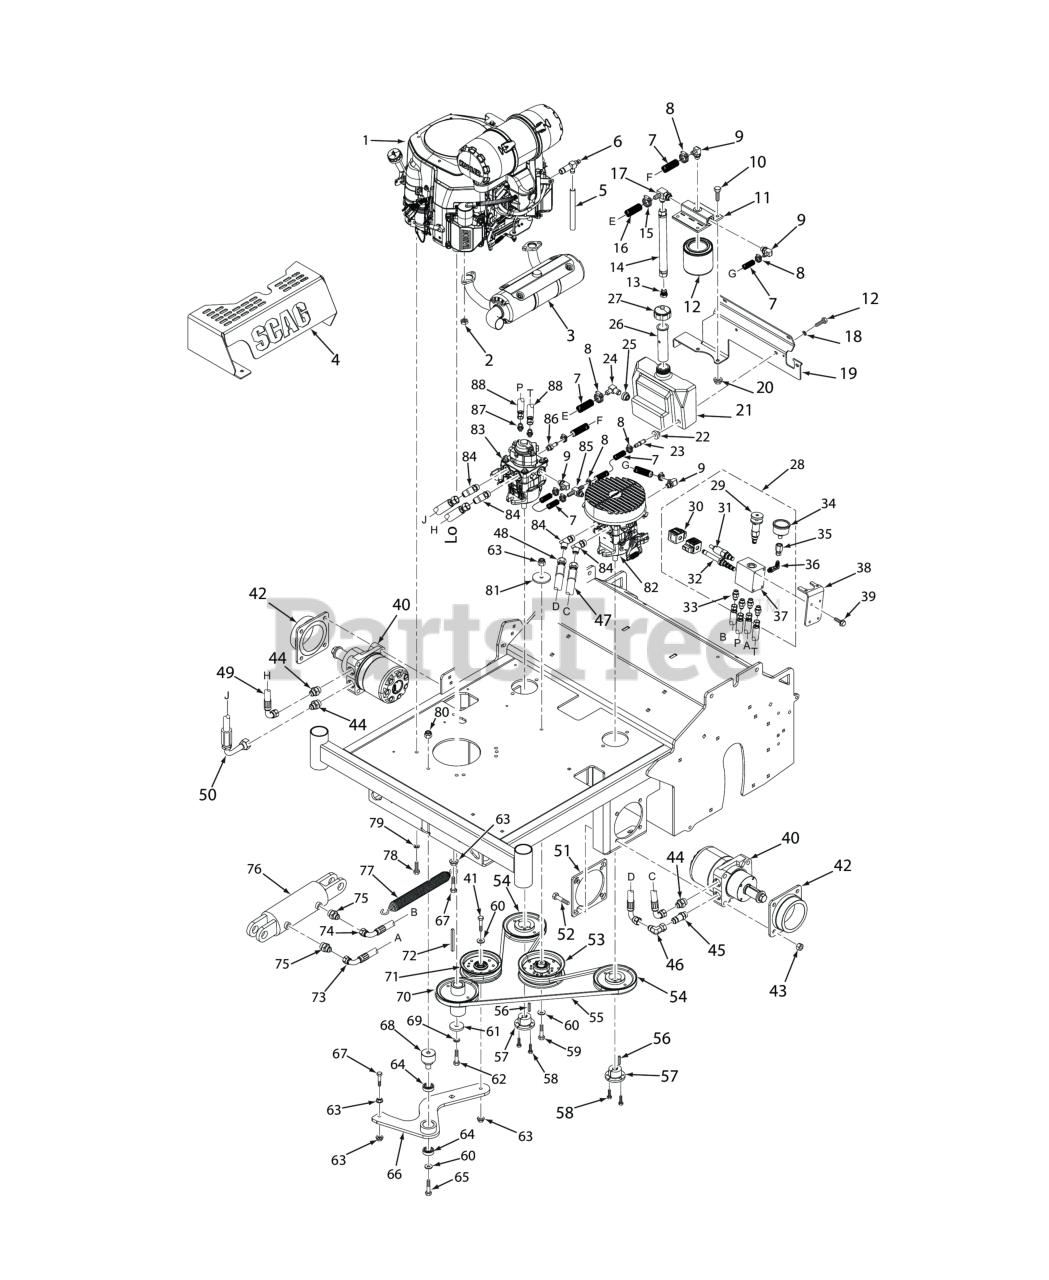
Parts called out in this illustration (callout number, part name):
1	Engine, Kohler - 23CV
2	Lock Nut, M8-1.25 -8H (Kohler)
3	Muffler, Kohler
4	Heatshield, Muffler
5	Tubing, Oil Drain 1/2 x 14"
6	Extension, Oil Drain 2.3" - Kawasaki
7	Hose, 3/8" ID - 10-1/4" Long (Order By The Inch)
8	Clamp, .69" Max. / .25" Min. Dia.
9	Elbow, 90 Degree - 9/16" O-Ring x 3/8" Hose
10	BOLT, SERRATED FLANGE HEX HEAD 5/16-18 X 3/4"
11	Filter Head Assembly
12	OIL FILTER, SPECIAL
13	Plug, JIC 3/4-16 UNF
14	Drain, Hose Assembly
15	Clamp, Cable 3/4" I.D.
16	Hose Assembly, 1/2" ID (Oil Reservoir to Filter Base)
17	Tee, 3/4" O-Ring x JIC x 1/2" Hose
18	Lockwasher, 5/16 (.317 x .586 x .078) Helical Spring
19	Bracket, Hydro Tank
20	Nut, Serrated Flange 5/16-18 (Right Front Engine Mounting, Briggs and Kohler Only)
21	Hydraulic Tank Assy.(incl. #22, 23, 24, 25, 26, 27)
22	Bushing, 0.56" Dia. Viton
23	Fitting, Straight
24	Fitting, 90 Degree - 1/2" Hose
25	Bushing
26	Insert, Filler Neck
27	CAP, HYDRAULIC TANK
28	Pressure Valve Assy. (incl. # 29 - 37)
29	Adjustable Valve Assy.
30	Adapter, Plug
31	Sensor, Valve
32	Sensor, Plug
33	Fitting, Valve
34	Pressure Gauge
35	Adapter
36	Elbow, 90 Degree O-Ring
37	Base, Valve
38	Mounting Brkt, Manifold
39	CAP SCREW, 1/4-20 X 1/2" SERRATED FLANGE HEX
40	Wheelmotor
41	Bolt, Hex Head 3/8-16 x 2-1/4" - 61"
42	Pivot Bearing Wlmt
43	Locknut, Hex 1/2-13 Center Lock
44	TUBE UNION, 3/4-16 JIC TO 7/8-14 "O" RING
45	Fitting, 1/2" JIC x 5/8" O-Ring (LH Wheel Motor - Upper Port Only)
46	Elbow, 1/2 JIC Female to 1/2 JIC Male
47	Hose Assembly
48	Hose Assembly
49	Hose Assembly
50	Hose Assembly
51	Plate Weldment, Motor Backing
52	Bolt, Hex Head 1/2-13 x 2-3/4" (48V & 52V - One Weight)
53	Idler Pulley, Belt Clutch
54	Pulley, 5.45 OD - Tapered Bore"
55	Belt, Pump Drive
56	KEY, 5 MM X 5 MM X 25 MM
57	Hub, Tapered, 15mm Bore
58	Bolt, Hex Head 1/4-20 x 1" Grade 8 Black
59	Capscrew, Hex Head 3/8-16 x 2.75"
60	Flatwasher, 3/8 (.391 x .938 x .105 HD) Grade 8
61	Flatwasher, 7/16-.469 x 1.75 x .25 (48, 52)
62	Bolt, Hex Head 7/16-20 x 2-1/4" w/Patch (Kawasaki)
63	HEX NUT, ELASTIC STOP LOCK, 3/8-16
64	BEARINGS, BALL, NEUTRAL RETURN
65	Bolt, Hex Head, 3/8-16 x 3-1/2"
66	Idler Arm Assy, Pump Drive (incl. #64)
67	Bolt, Hex Head 3/8-16 x 1-1/2" Grade 8 Black
68	Pivot, Idler
69	Lockwasher, 7/16� Spring
70	Pulley, 5.45 Dia. 1.125 Bore
71	Pulley, Idler 4-1/2"
72	Key, 1/4 x 1/4 x 3-1/4�
73	Hose Assembly
74	Hose Assembly
75	Fitting, Valve
76	Cylinder, 3.00 Bore x 4.00 Stroke
77	Spring, Transmission Drive
78	Bolt, Hex Head 3/8-16 x 1-1/4", Kawasaki FX / FT & FT-EFI
79	Lockwasher, 3/8" Spring, Kawasaki FX / FT & FT-EFI / B&S 32BV
80	Bolt, Hex Hd. 1/2-13 x 9-1/2"
81	Flatwasher, 3/8-.406 x 2.25" x .1875
82	Pump, LH
83	Pump, RH
84	Elbow, 45 Deg. - 3/4-16 JIC Male x Male 3/4-16 O-Ring
85	Tee Fitting, O-Ring to Barb
86	Fitting, 9/16" O-Ring x 3/8" Hose
87	Union, 37 Degree 9/16-18 x 7/16-20 O-Ring
88	Hose Assembly
